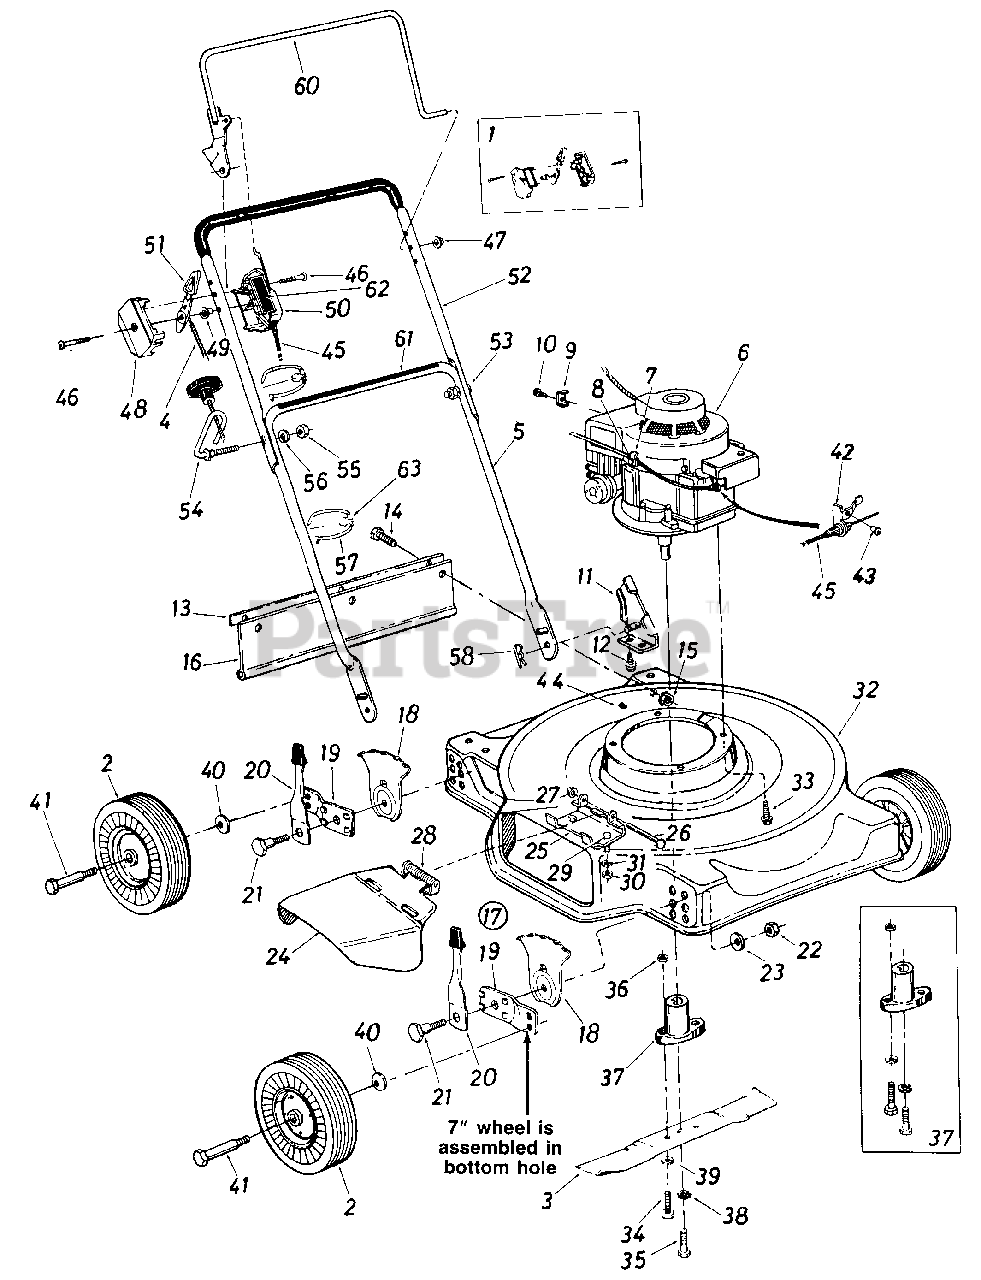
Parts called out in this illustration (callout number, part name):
1	KIT-THROTTLE CONTROL
2	WHEEL ASSY W/TIRE
3	WHEEL ASSY W/TIRE
4	CABLE-THROTTLE
5	LOWER HANDLE
7	CLAMP-CASING
8	SCREW-HEX B-TAP #10 X .38
9	CLAMP-CONDUIT
10	SCREW-HEX WASH HD AB-TAPP #8 X .38
11	BRACKET ASSY-HDLE
12	SCREW-HEX WASH HD 5/16-18X1/2
13	STRIP-RETAINING
14	SCREW-HEX 1/4-20 C .62
15	NUT-SEMS 1/4-20
16	FLAP-RR
17	ADJUSTER ASSY-HGT-RH
18	PLATE-HGT ADJ
19	BAR-PIVOT
20	LEVER & KNOB ASSY
21	SCREW-SHLD
22	NUT-HEX 3/8-16
23	WASHER-BELL
24	DEFLECTOR ASSY-CHUTE
25	PLATE-ADAPTER
26	PIN-PIVOT
28	SPRING-TORSION
29	SCREW-HEX 1/4-20 X .50
30	NUT-HEX 1/4-20
31	LOCK WASHER 1/4 DIA
34	SCREW-HEX SPECIAL 5/16-24X1.0
35	SCREW-HEX 3/8-24 X 2.25
36	NUT-5/16-24
37	KIT-BLADE ADAPTER
38	WASHER-HDL 3/8
39	WASHER-LOCK-5/16
40	WASHER-BELL .400 ID X .88 X .060
41	SCREW-SHLD .498 DIA X 1.450
42	BRACKET-CABLE
45	WIRE-THROTTLE
46	SCREW-TRUSS MACH
47	NUT-SPEED
48	PANEL HALF-CONTROL
49	PIN-CONTROL DISC
50	PANEL HALF-CLUTCH
51	LEVER-THROTTLE CONT-REV
52	HANDLE-UPPER
53	BOLT-CARRIAGE-CURV 5/16-18 X 1.38
54	SCREW-RECOIL HANDLE GUIDE
55	NUT-HEX 5/16-18
56	WASHER-LOCK-5/16
57	TIE-CABLE
58	PIN-INTERN COT-5/16 DIA
60	HANDLE ASSY-CONTROL-RH
63	TIE-CABLE
